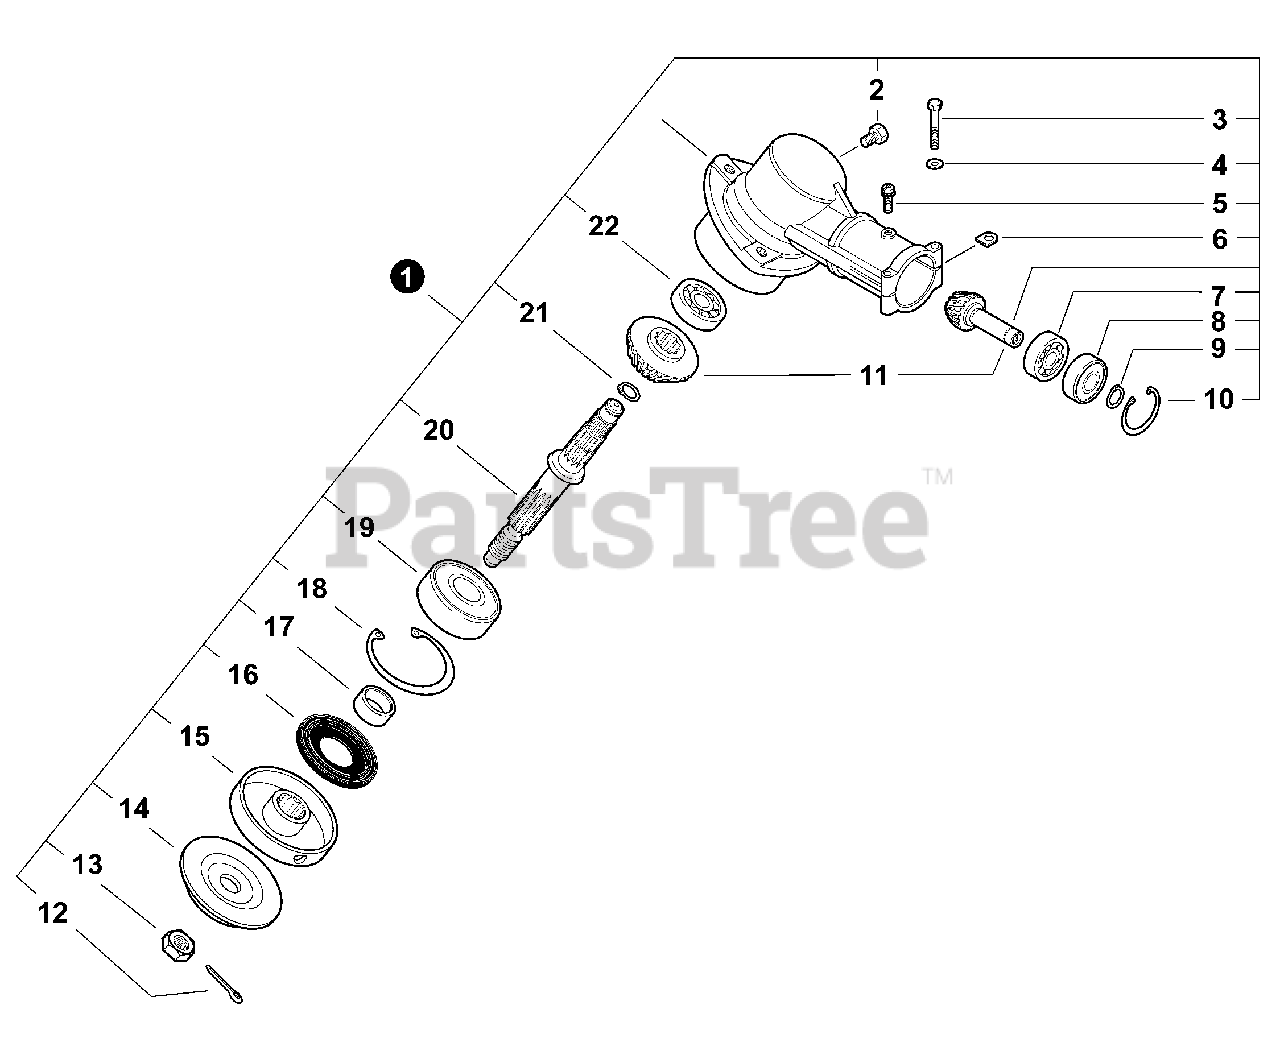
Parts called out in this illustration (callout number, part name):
1	GEAR CASE ASSY
2	BOLT M8×8
3	BOLT 5×35 SP
4	WASHER, FLAT 5.5×10×0.8
5	SCREW 5×10
7	BEARING, BALL 6900
8	BEARING, BALL 6900Z
9	RING, SNAP Ø10
10	RING, SNAP Ø22
11	GEAR SET
12	PIN, COTTER 2×22
14	PLATE, ADAPTOR - LOWER
15	PLATE, ADAPTOR - UPPER
16	SEAL, OIL 22
17	SPACER 11.8×15×9
18	RING, SNAP Ø32
19	BEARING, BALL 6201
20	SHAFT, GEAR
21	RING, SNAP Ø12
22	BEARING, BALL 609
